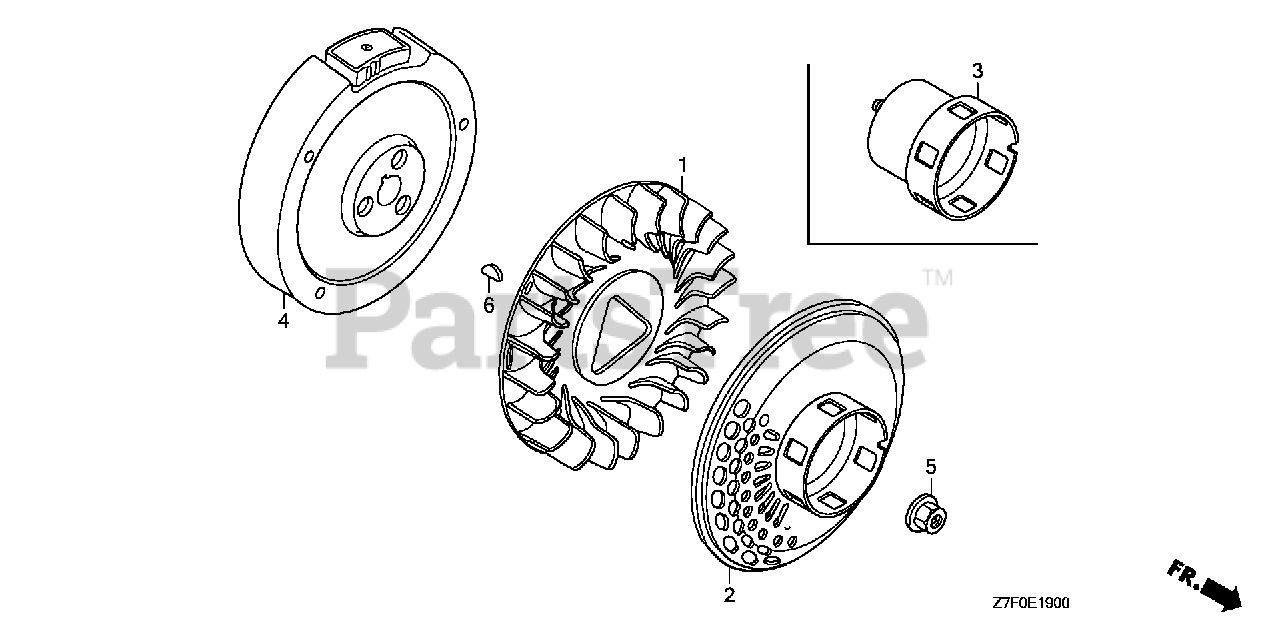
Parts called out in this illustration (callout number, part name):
1	FAN, COOLING
3	PULLEY, STARTER
5	NUT, SPECIAL (16MM)
6	KEY, SPECIAL WOODRUFF (25X18)
